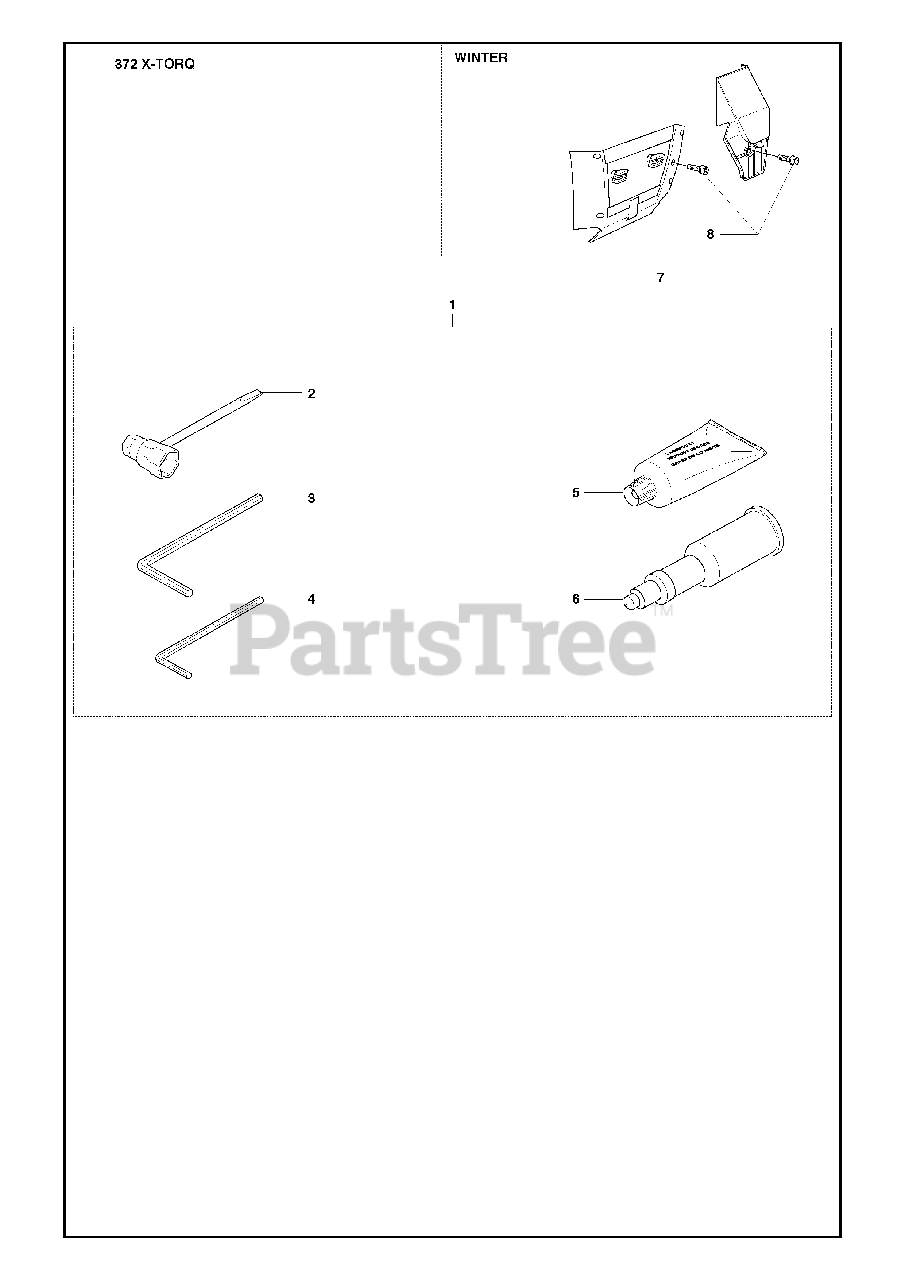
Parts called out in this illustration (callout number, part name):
1	TOOL KIT
2	COMBI TOOL
3	L-SPANNER
4	L-SPANNER
5	GREASE
6	Grease Gun
7	WINTER KIT
